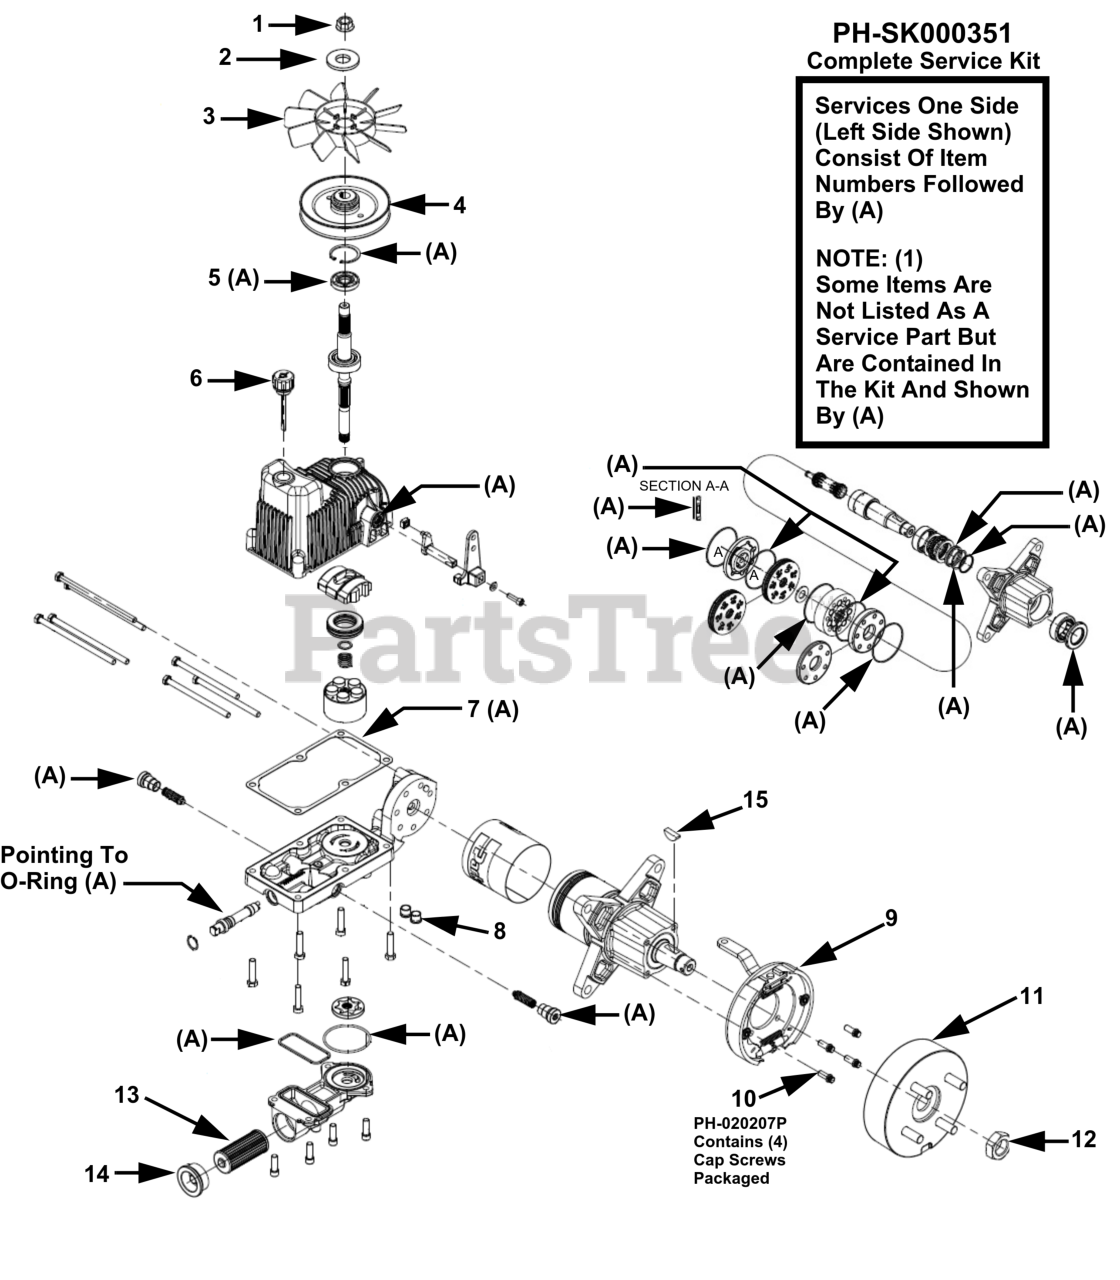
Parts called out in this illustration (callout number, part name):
1	NUT-FLANGE 1/2-20
2	FAN SPACER
4	PULLEY (SPLINED)
6	BREATHER
8	PLUG-MAGNETIC HEX
9	BRAKE ASSEMBLY-ON HOLE LEVER
10	SCREW-CAP (QTY 4)
11	DRUM-4 BOLT BRAKE
12	LOCK NUT - 1-20
14	PLUG & O-RING ASSE
15	WOODRUFF KEY
16	ROTATING BRACKET
A	COMPLETE SEAL SERVICE KIT
